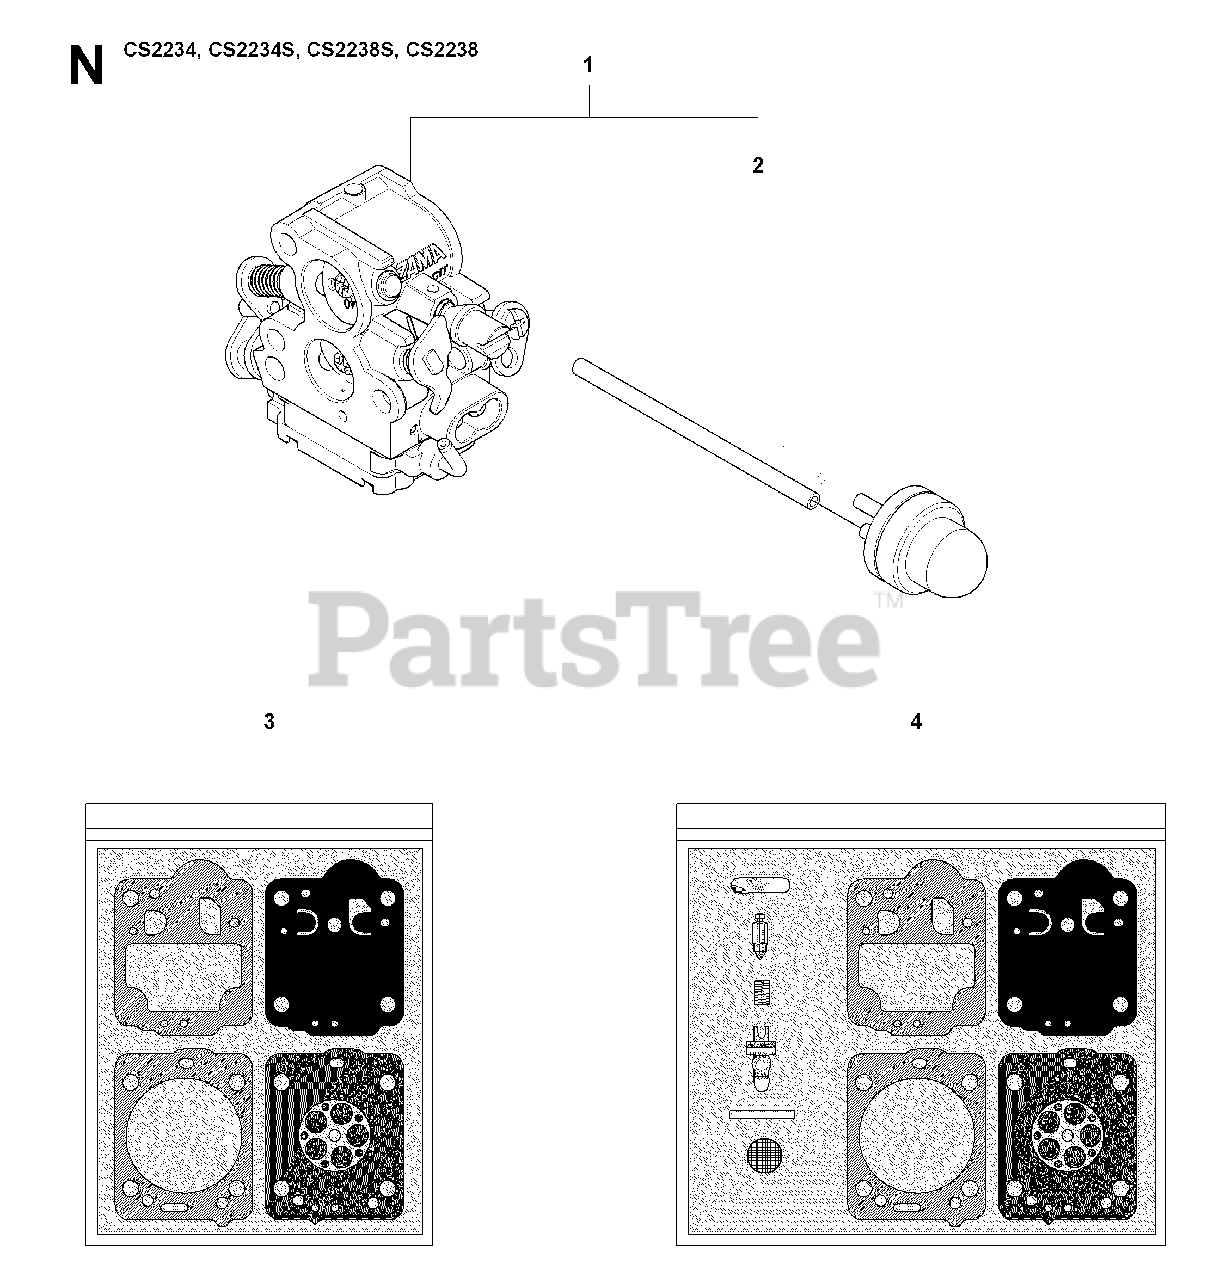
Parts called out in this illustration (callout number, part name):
1	%CARBURETOR
2	PURGE & LINE ASSY
3	KIT CARB GASKET
4	KIT CARB REPAIR
